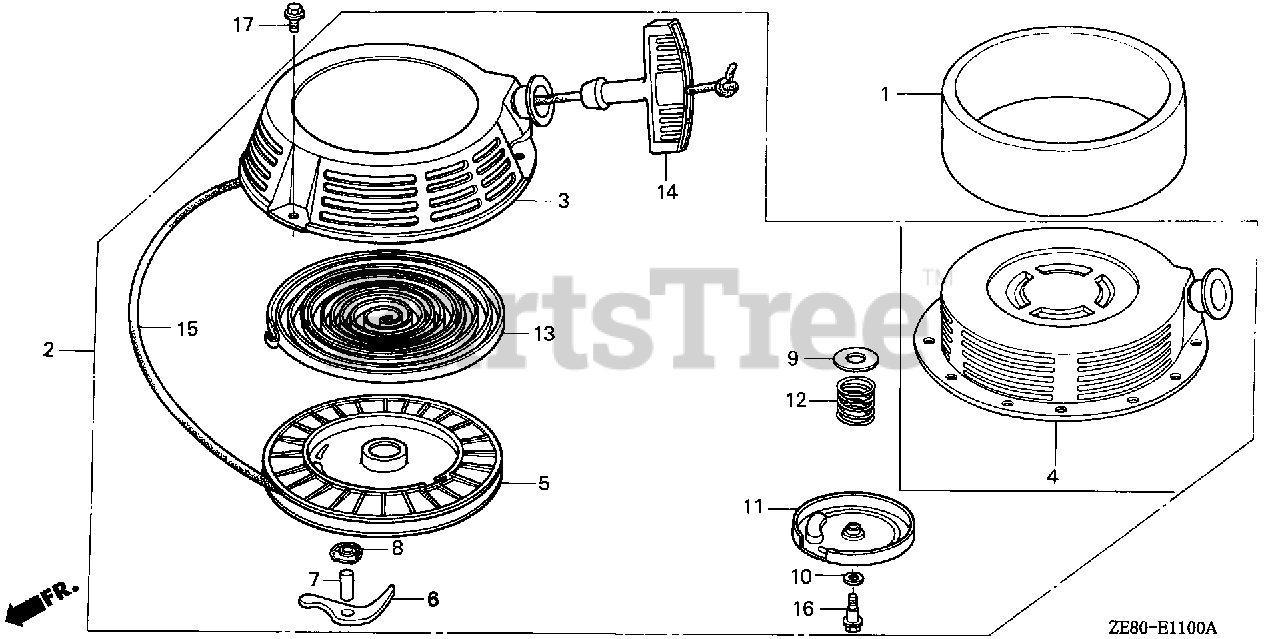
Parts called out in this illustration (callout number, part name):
1	FILTER, AIR
2	STARTER ASSY., RECOIL *R8* (BRIGHT RED)
4	CASE, RECOIL STARTER *R8* (BRIGHT RED) (NOT AVAILABLE)
5	REEL, STARTER
6	RATCHET, STARTER
7	SHAFT, RATCHET (NOT AVAILABLE)
8	PLATE, GUIDE
9	PLATE A, FRICTION
10	PLATE B, FRICTION
11	COVER, STARTER REEL
12	SPRING, FRICTION (D=18.5MM / L=20.5MM)
12	SPRING, FRICTION (D=13.0MM / L=16.3MM)
13	SPRING, RETURN
14	GRIP, STARTER
15	ROPE, STARTER (N/A: USE ALT P/N 08560-ZG921-11)
16	BOLT, REEL COVER
17	BOLT, FLANGE (6X10) (NOT AVAILABLE)
17	BOLT, FLANGE (6X8)
